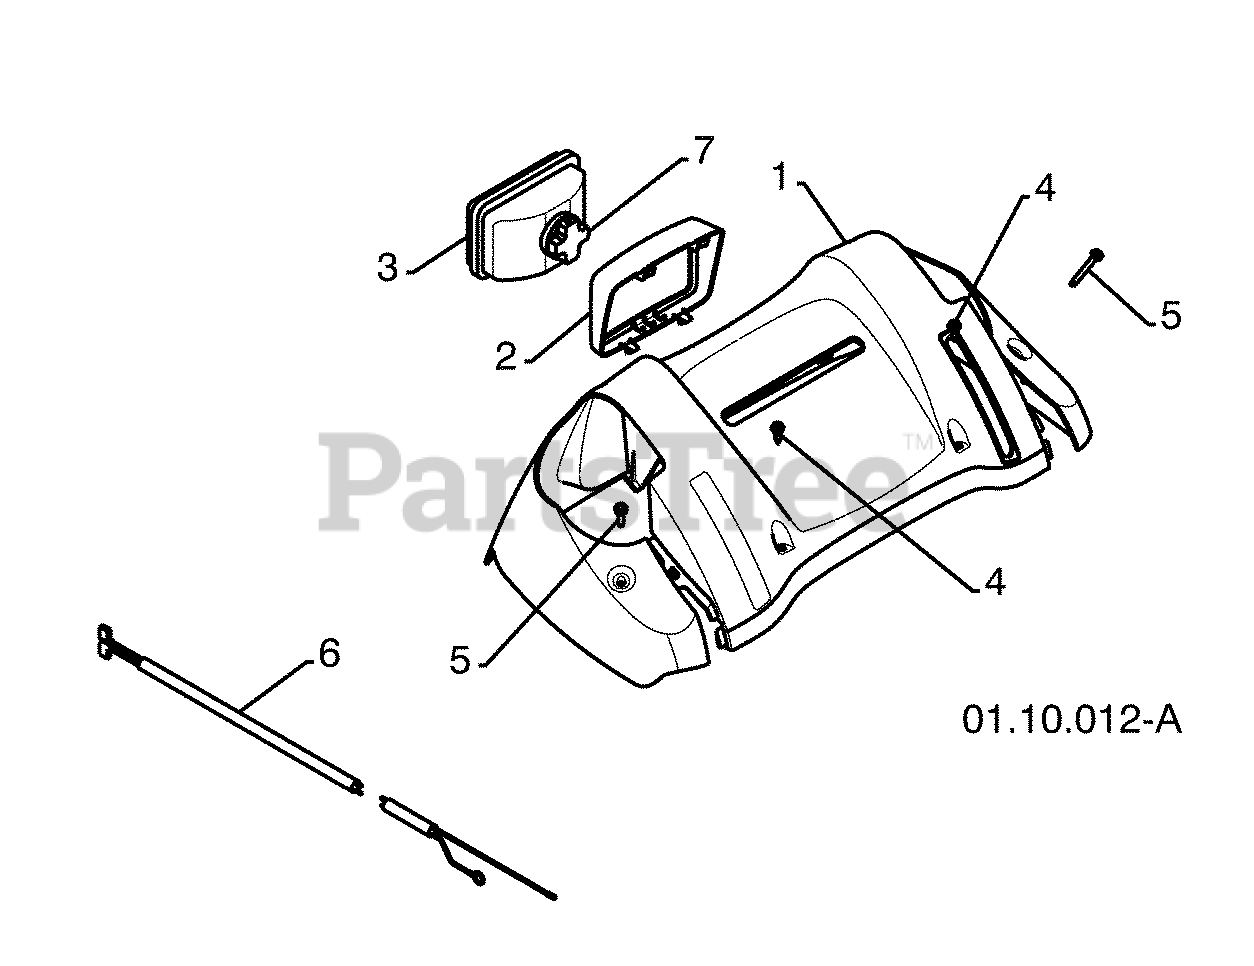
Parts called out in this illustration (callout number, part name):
1	CONSOLE PANEL GRAY
2	HEADLIGHT BEZEL GRAY
3	FLOOD HEADLIGHT
4	SHOULDER SCREW 10--24 X .625
5	SCREW 10--24 X 1.25
6	WIRE HARNESS
